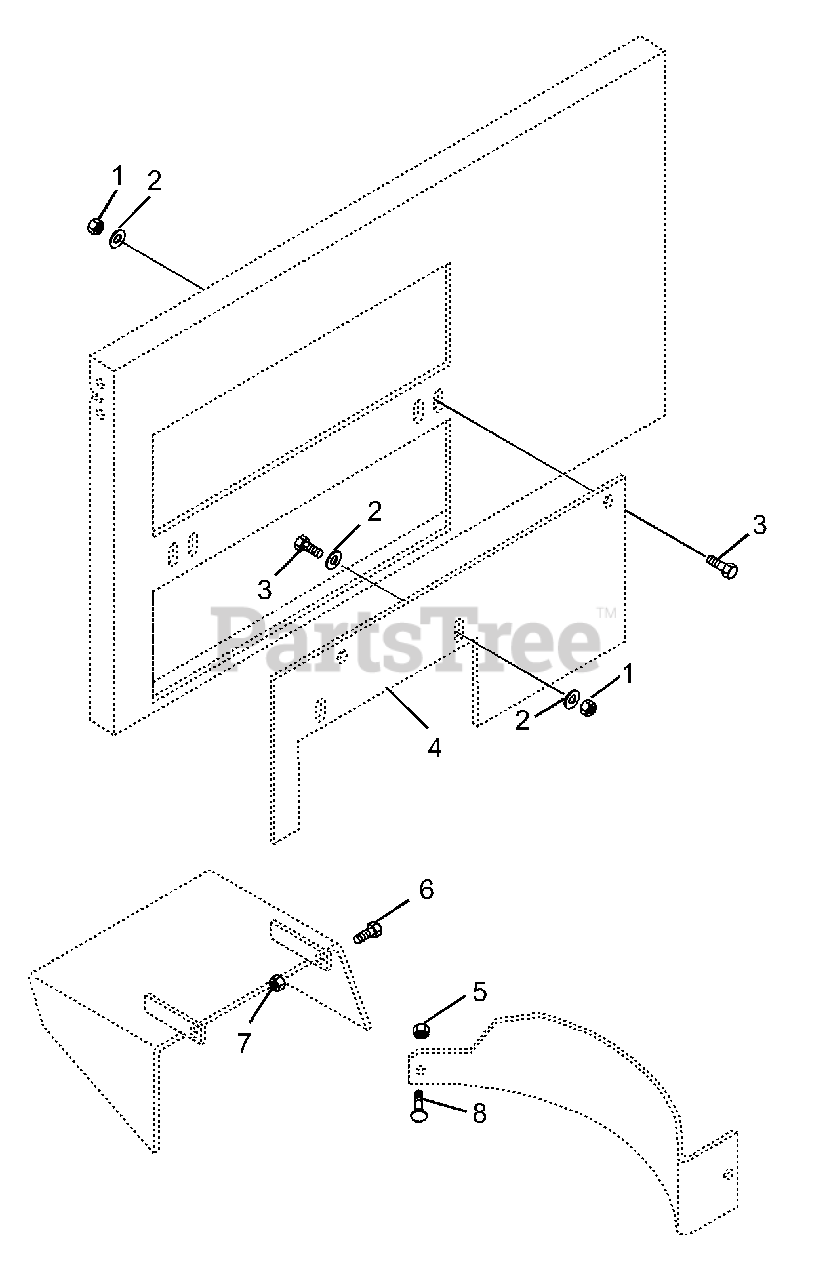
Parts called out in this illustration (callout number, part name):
1	Nut-Locking-Nylon .375-16 Grade 2
2	Washer-Flat-Steel .406 x .812 x .065
3	Bolt-Hex .38-16 x 1.00 Grade 5
4	Adapter, PRO 40
5	Nut-Locking-Nylon .250-20 Grade 2
6	Bolt-Hex .31-18 x 1.25 Grade 5
7	Nut-Locking-Nylon .312-18 Grade 2
8	Bolt-Round Head Square Neck .25-20 x .75
